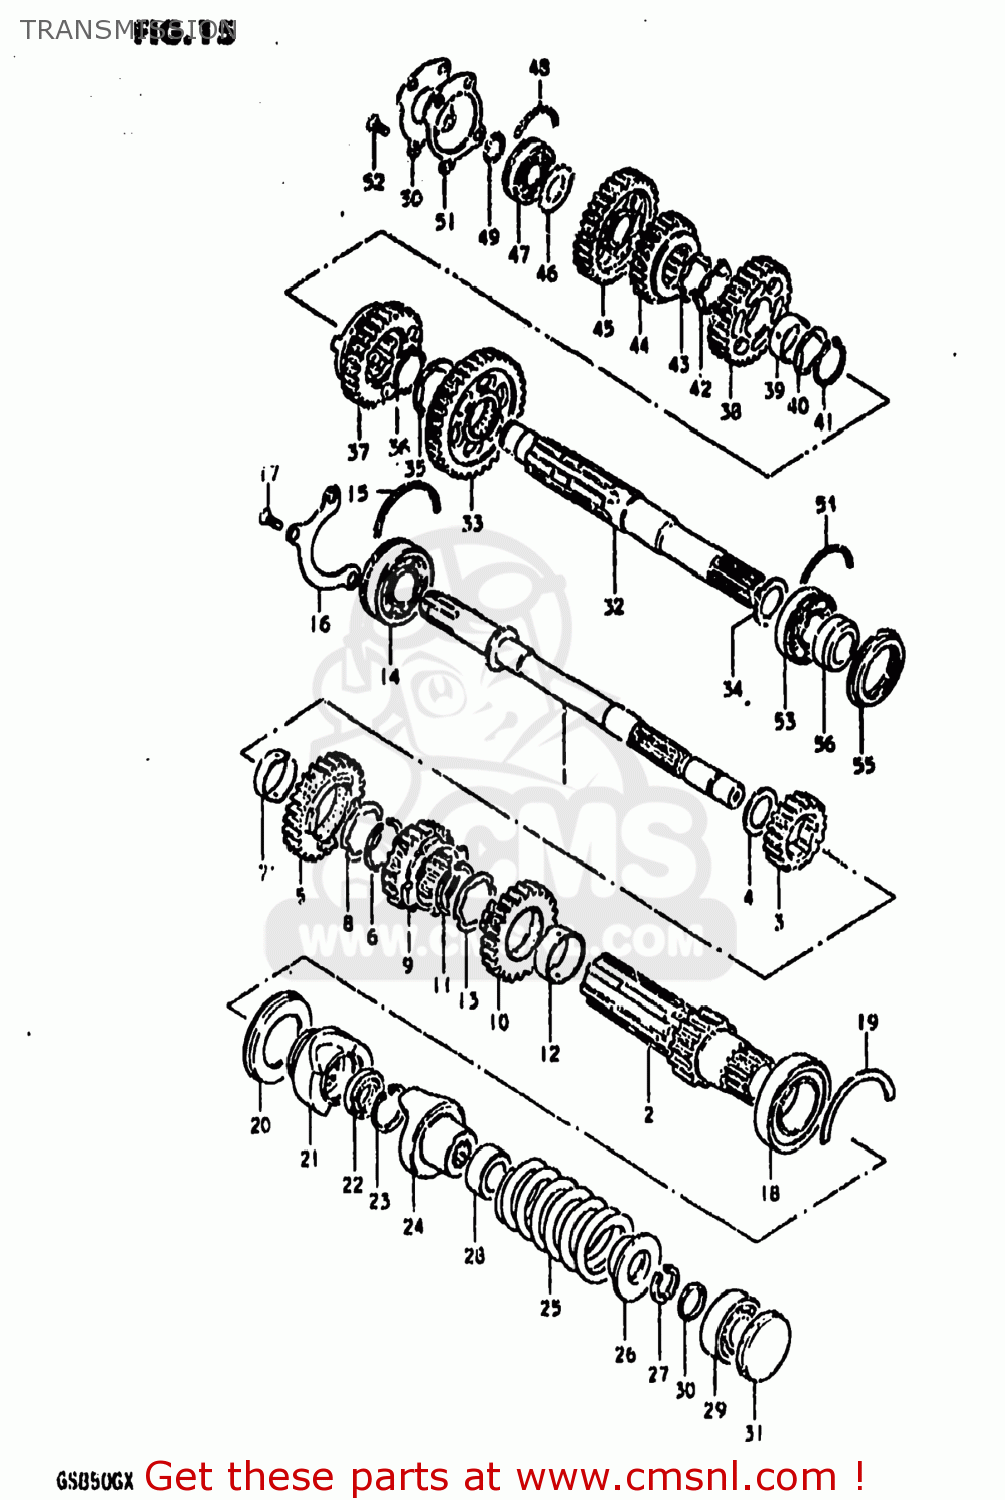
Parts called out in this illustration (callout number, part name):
1	SHAFT,COUNTER
2	SHAFT,OUTER COUNTER
3	GEAR,SECOND DRIVE
4	WASHER (21X35X2)
5	GEAR,5TH DRIVE(NT:26)
6	RING,SNAP
7	SPACER,DRIVE GEAR
8	LOCK WASHER,5TH DR GEAR SPACER
9	GEAR,THIRD DRIVE
10	GEAR,FOURTH DRIVE
11	RING,SNAP
12	SPACER,DRIVE GEAR
13	LOCK WASHER,5TH DR GEAR SPACER
14	BEARING(25X62X17)
15	C-RING
16	RETAINER,CNTR SHAFT BEARING
17	SCREW
18	BALL BEARING 32X58X13
19	C-RING
20	SEAL,OIL(40X58X7)
21	DOG,OUTPUT CAM
22	SEAL,OIL(20.6X31X6)
23	CIRCLIP
24	DOG,INPUT CAM
25	SPRING
26	STOPPER,CAM DOG
27	STOPPER,CAM DOG
28	GUIDE,CAM DOG SPRING
29	BEARING
30	SPACER (17X21X3.5)
31	PLUG
32	SHAFT,DRIVE
33	GEAR,FIRST DRIVEN
34	WASHER, LH
35	WASHER,LOCK
36	CIRCLIP
37	GEAR,FOURTH DRIVEN
38	GEAR,THIRD DRIVEN
39	BUSH,3RD DRIVEN GEAR
40	WASHER,LOCK
41	CIRCLIP
42	WASHER
43	WASHER,LOCK
44	GEAR,FIFTH DRIVEN
45	GEAR,SECOND DRIVEN
46	WASHER
47	BEARING(20X47X14)
48	C RING
49	CIRCLIP
50	PLATE,DRIVESHAFT
51	GASKET,DRIVESHAFT PLATE (MCA)
52	SCREW
53	BEARING
54	C RING
55	SEAL,OIL(35X52X6)
56	SPACER,DRIVESHAFT,LEFT
